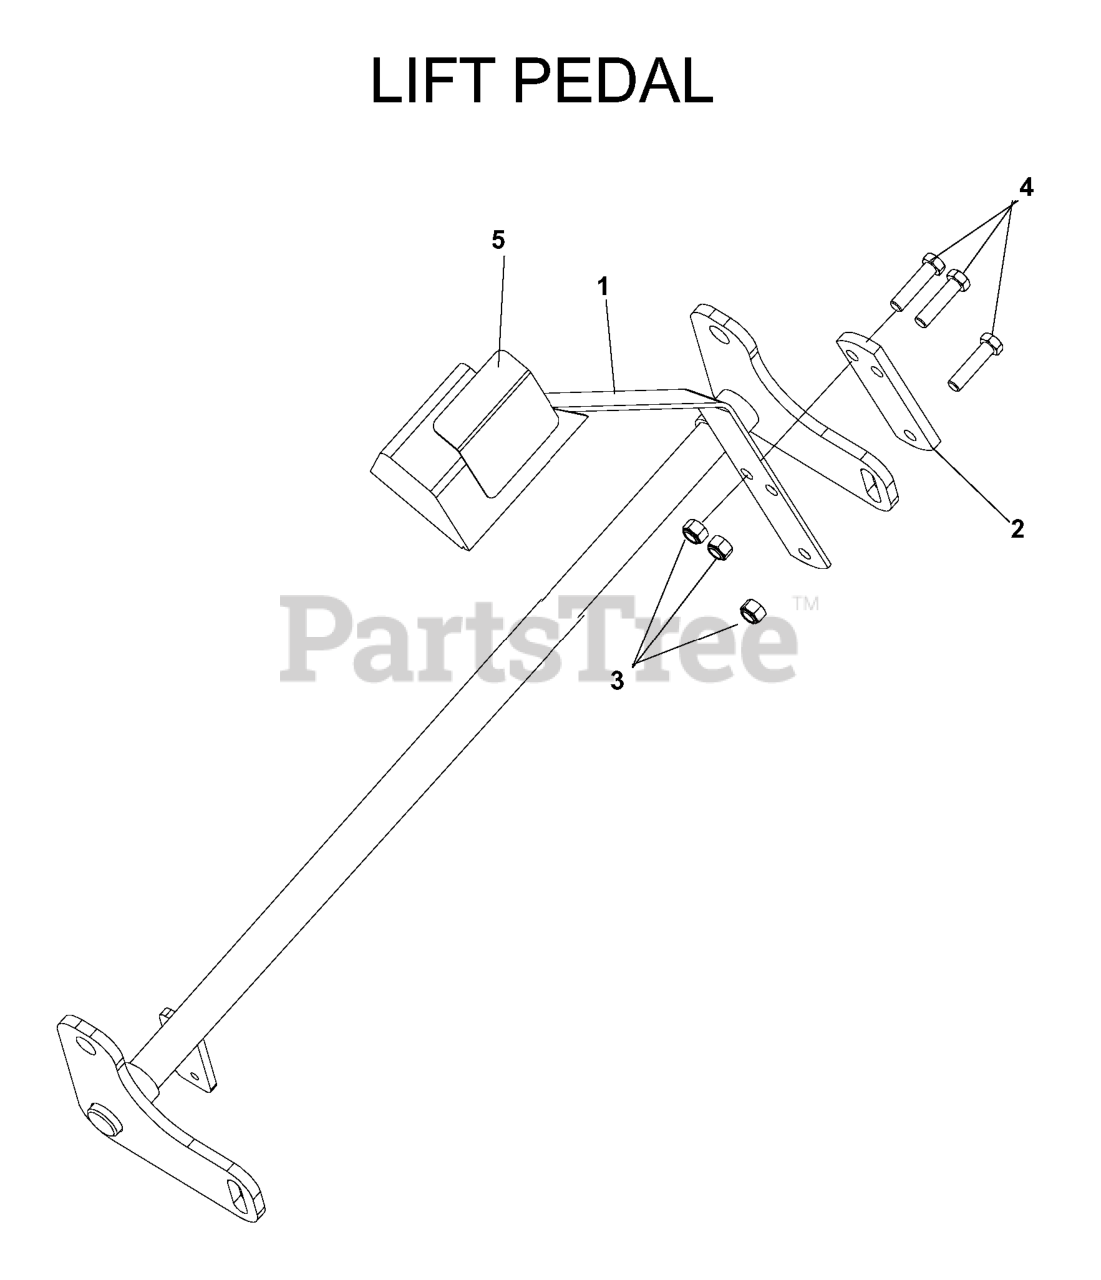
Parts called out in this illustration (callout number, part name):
1	LIFT PEDAL W/PAD
2	TIGHTENING PLATE
3	NUT 3/8-16 NYLOC
4	HCS 3/8C X 1 1/2
5	ANTI-SKID PAD
